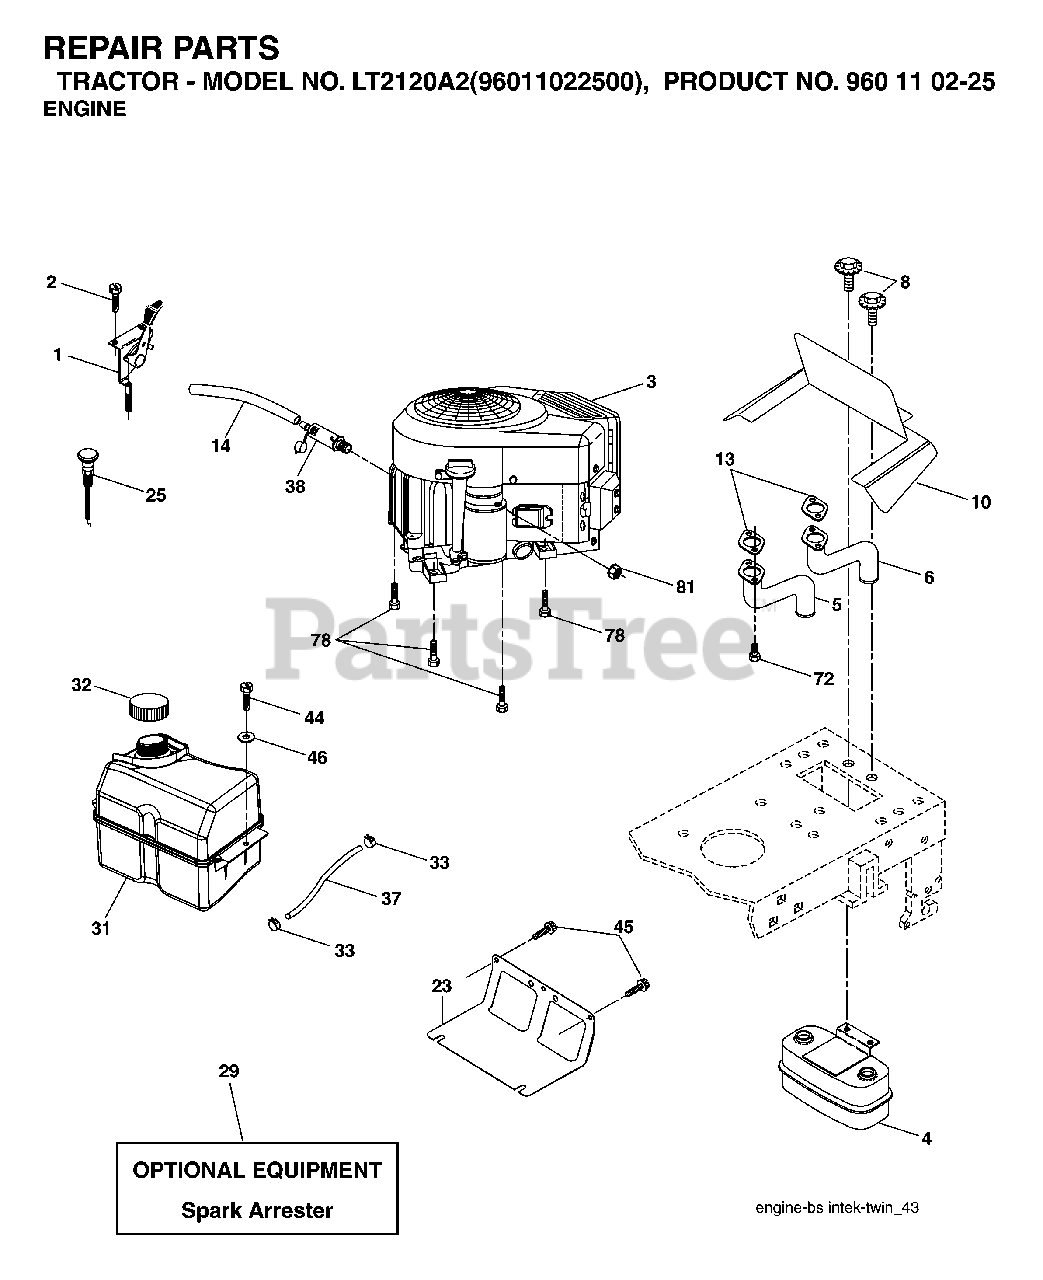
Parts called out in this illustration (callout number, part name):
1	THROTTLE CABLE
2	SCREW
4	MUFFLER.TWIN.CYL.LOW.TONE
5	TUBE MANIFOLD LH
6	EXHAUST TUBE RH
8	BOLT, 5/16-18 X 1 3/4
10	SHIELD.BROWNING.B&S
13	GASKET.MUFFLER
14	TUBE, DRAIN OIL ASM.
23	SHEILD.BROWNING.DBR.GUARD
25	CONTROL CHOKE
29	ARRESTER SPARK (OPTIONAL)
31	TANK FUEL
32	FUEL CAP
33	HOSE CLAMP
37	LINE.FUEL.20
38	PLUG DRAIN OIL EASY
44	SCREW HEXWSHR 1/4-20X3/4
45	SCREW, 3/8-16X3/4
72	SCREW.SOCKET.HEAD.5/16-18
81	NUT
